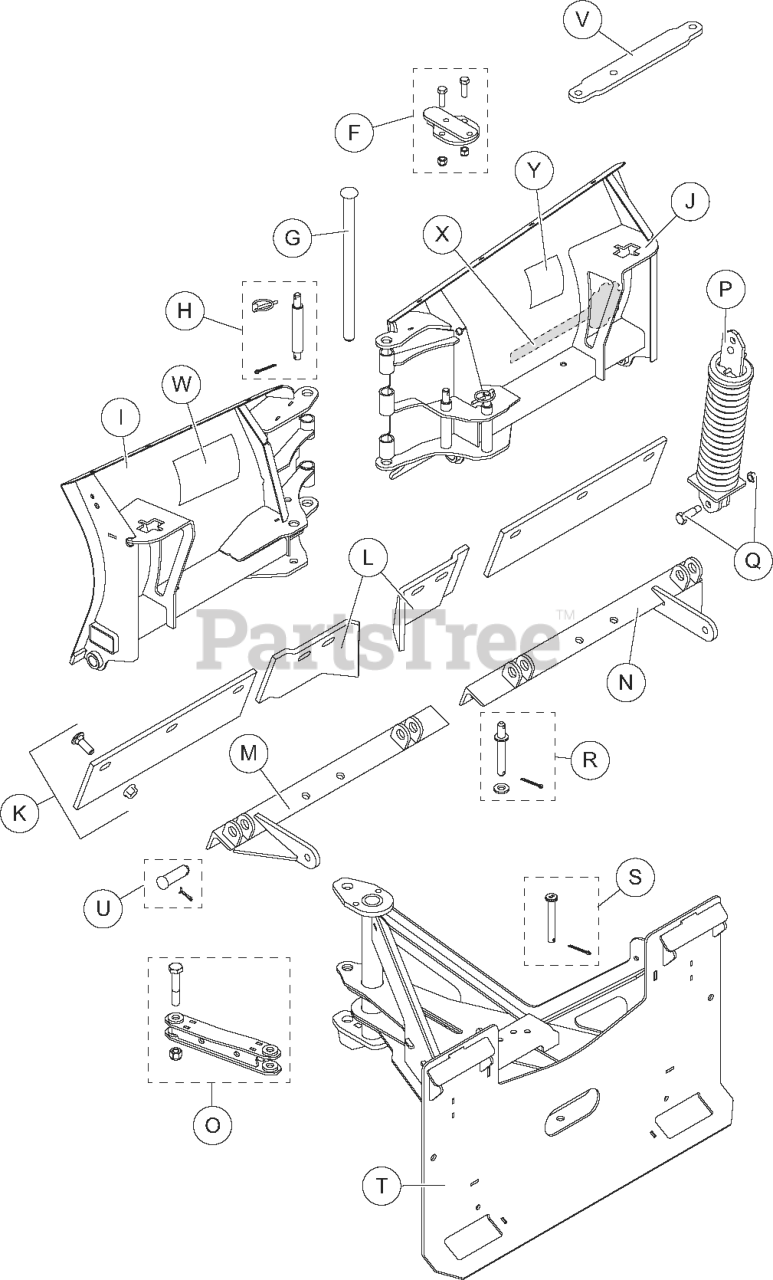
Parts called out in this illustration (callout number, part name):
F	PKG, PIN HOLD DOWN
G	.750 X 12-.625 PIN
H	PKG, WING PIN
I	V-PLOW, BLADE LH
J	V-PLOW, BLADE RH
K	PKG, CUTTING EDGE W/ FASTENERS
L	PKG, CTR CUTTING EDGE W/ FASTENERS
M	BASE ANGLE, LH
N	BASE ANGLE, RH
O	PKG, DRIVE LINK
P	PKG, TRIP SPRINGS
Q	PKG, SHOULDER BLT W/ LOCKNUT
R	PKG, DRIVE PIN
S	PKG, PIN
T	A-FRAME
U	PKG, .750 X 2-.188 PIN
W	DECAL, CONFIGURATION V-PLOW
X	DECAL, ARIENS LOGO W/ BADGE
Y	DECAL, WARNING/CAUTION V-PLOW
